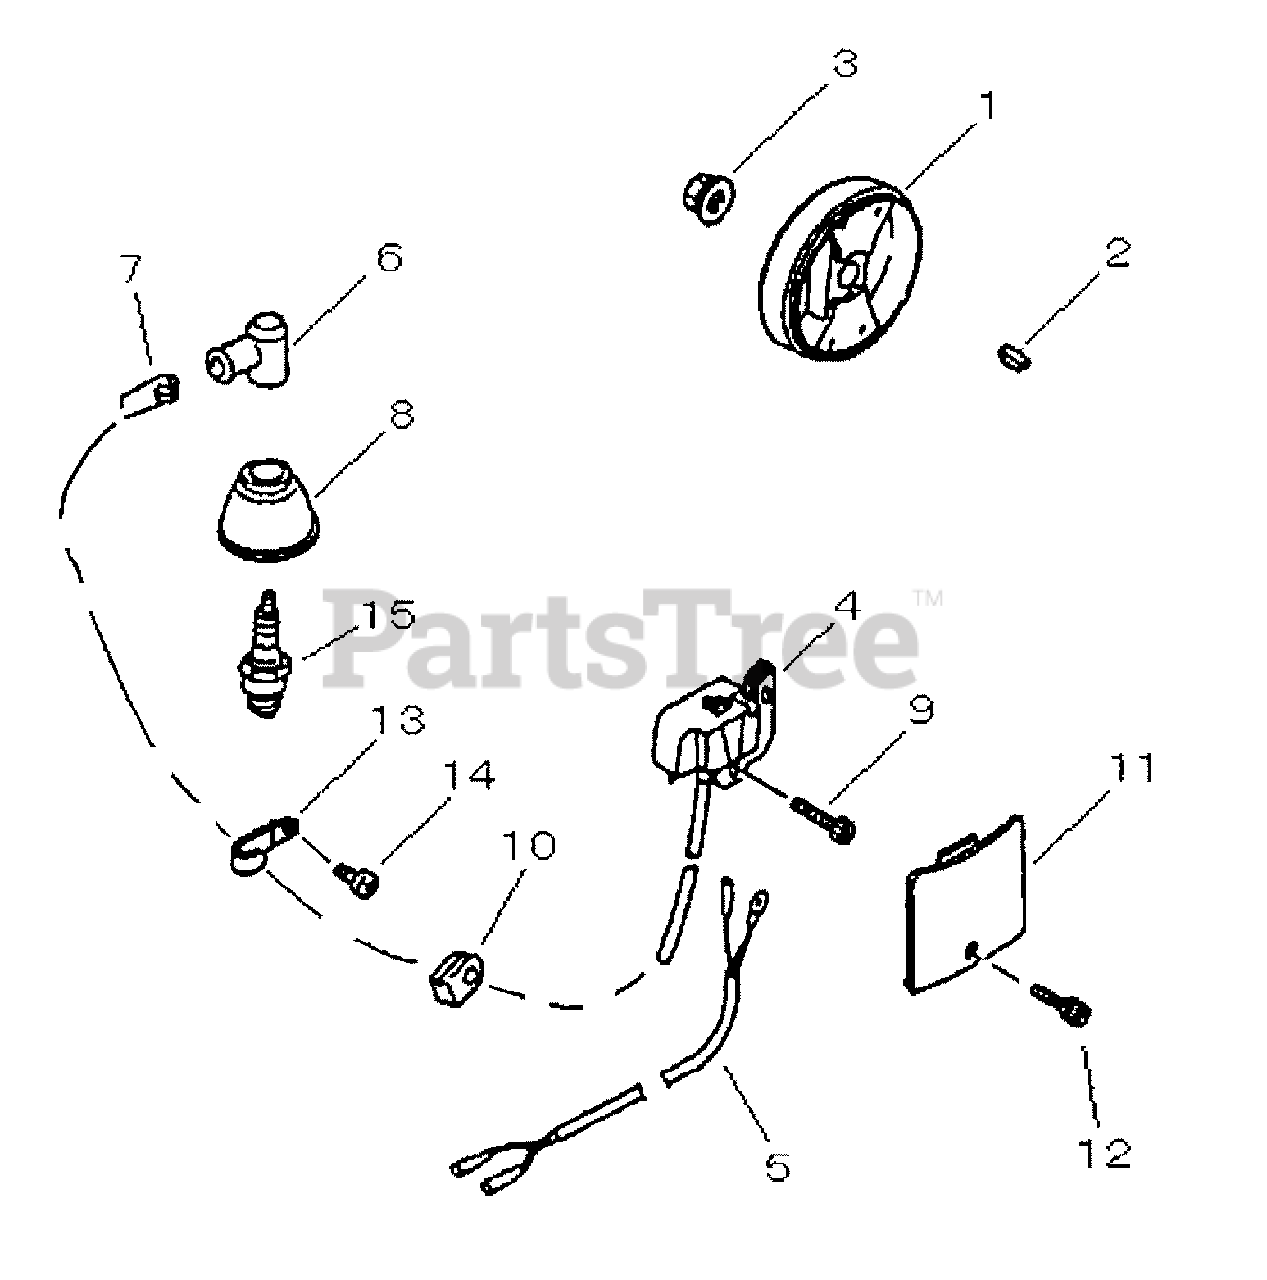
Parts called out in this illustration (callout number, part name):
1	FLYWHEEL
2	KEY
3	NUT, FLANGE M10
4	COIL, IGNITION
5	LEAD - IGNITION
6	CAP, SPARK PLUG
7	TERMINAL
8	COVER, SPARK PLUG
9	BOLT M4×20
10	GROMMET
12	BOLT M4×16
13	CLIP
14	SCREW, TAPPING 5×14
15	SPARK PLUG - RCJ6Y
